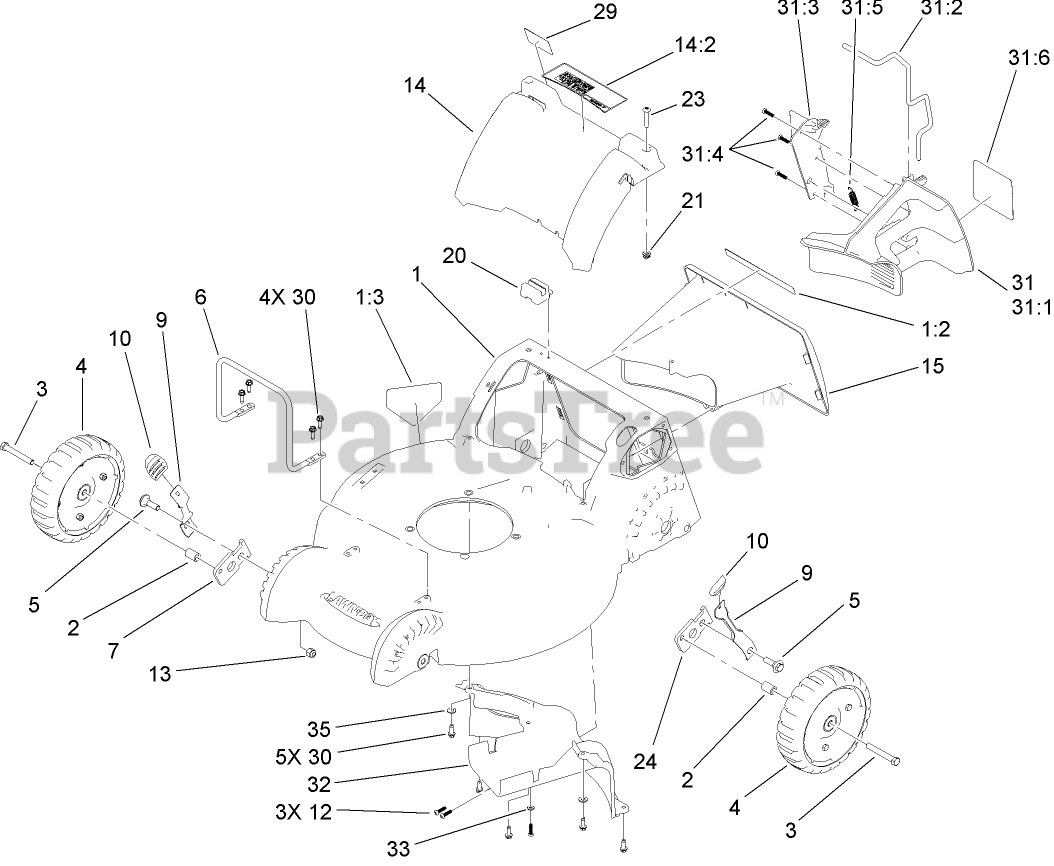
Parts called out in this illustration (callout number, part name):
1	HOUSING
1:2	DECAL-SAFETY
1:3	DECAL-DANGER
2	SPACER
3	SCREW-HH
4	8 INCH WHEEL ASM
5	SCREW-SHOULDER, HWH
6	GUARD-ENGINE
7	ARM-PIVOT, RH
9	ARM-SPRING, FRONT
10	Knob-Lever, HOC
12	SCREW-PLASTITE
13	NUT-LOCK, NI
14	COVER-REAR
14:2	DECAL-SAFETY
15	TUNNEL
20	MODULE-SWITCH
21	NUT-CLIP
23	SCREW-PTH
24	ARM-PIVOT, LH
29	DECAL-BAG ATTACHMENT
30	SCREW-HWHTF
31	MULCH PLUG ASM
31:1	PLUG-MULCH, LH
31:2	LATCH-PLUG, MULCH
31:3	PLUG-MULCH, RH
31:4	SCREW-PLASTITE
31:5	SPRING-EXTENSION
31:6	DECAL-PLUG, MULCH
32	BAFFLE-REAR
33	WASHER-FLAT
35	WASHER-FLAT
